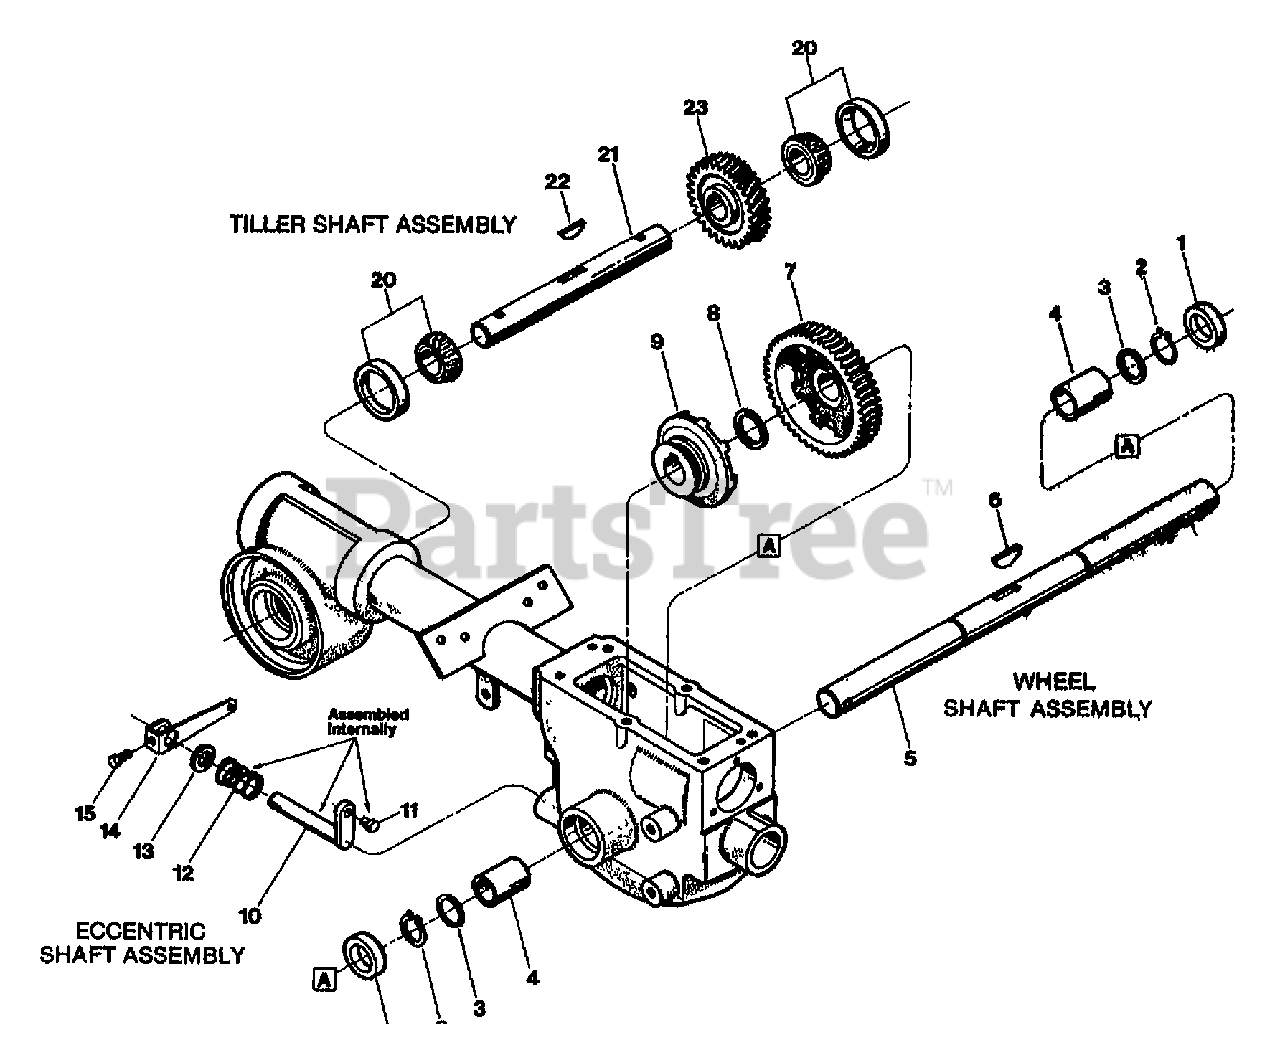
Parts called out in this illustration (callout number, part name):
1	SEAL-OIL WHEELSHAFT
2	RING-HEAVY EXT .906 ID
3	SHIM-1.375X1.015X.062
3	SHIM-1.375X1.015X.03
3	SHIM-1.375X1.015X.015
3	SHIM-1.375X1.015X.01
4	BUSHING-1.25X1.005X1.5
5	WHEELSHAFT W/KEY
6	KEY-HI PRO .25X1.312
7	GEAR-WORM 46 TEETH MACH
8	WASHER-1.468X1.016X.062
9	CLUTCH-MACH
10	WELD-ECCENTRIC
11	PIN-.375 X .72
12	SPRING-.850 X .875 LONG
13	SEAL-OIL ECCENTRIC
14	LEVER-CABLE ADJ PNT
15	SCR-HH 1/4-20X.5 GR5 YEL
20	BEARING CUP & CONE (W/RACE)
21	SHAFT W/KEY (TILLER)
22	KEY-WOODRUFF .25X1.12
23	GEAR-TILLER MACH
